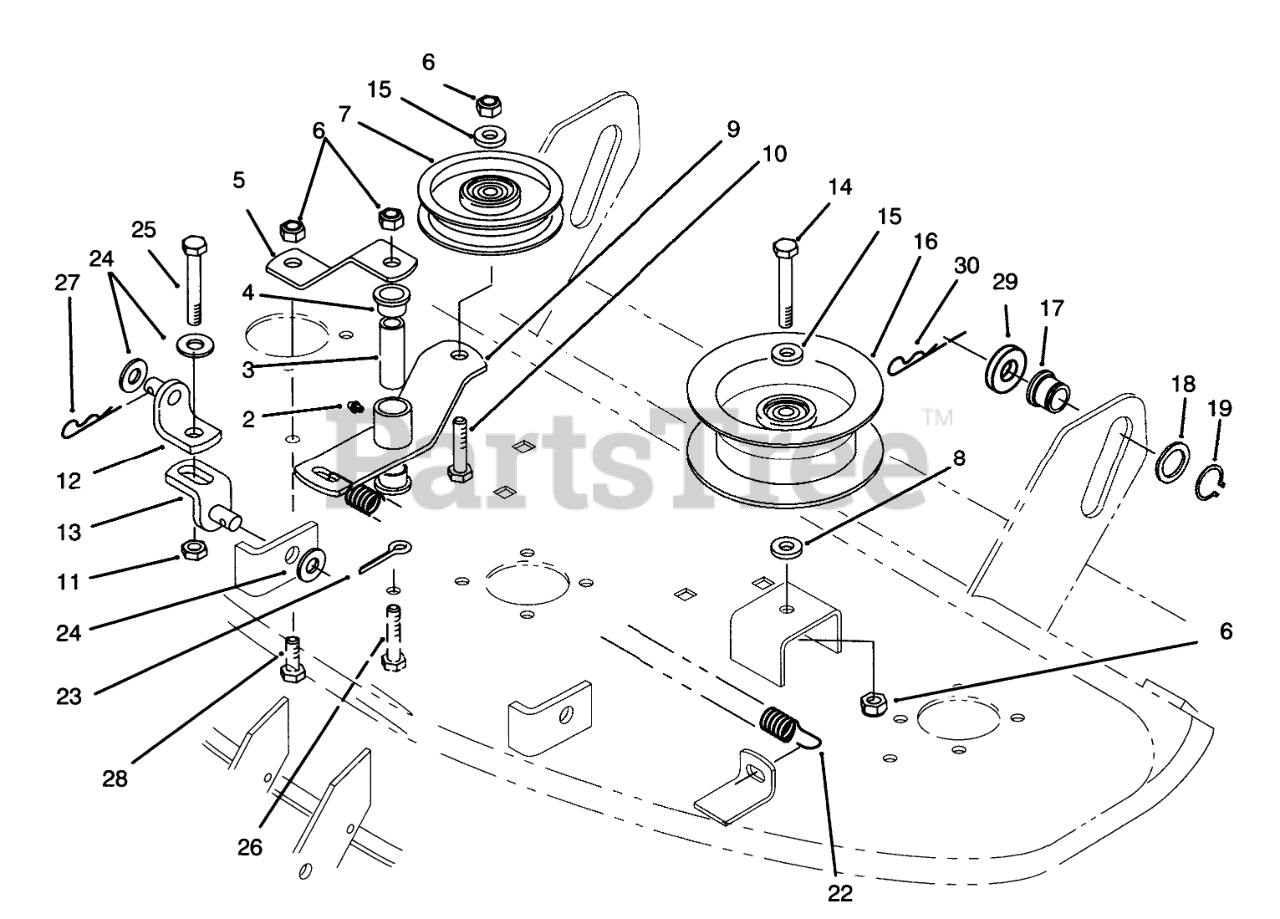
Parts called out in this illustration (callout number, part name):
2	FITTING-GREASE
3	SPACER
4	BUSHING
5	STRAP-BRACE
6	NUT-LOCK, NI
7	PULLEY-IDLER, FLAT
8	WASHER
9	Arm
10	SCREW-HH
11	NUT-JAM
12	BRACKET-LIFT, UPPER
13	BRACKET-LIFT, LOWER
14	SCREW-HH
15	WASHER-FLAT
16	PULLEY-IDLER
17	ROLLER-LIFT
18	Washer
19	RING-RETAINING
22	Spring-Extension
23	PIN-COTTER
24	WASHER-FLAT
25	SCREW-HH
26	SCREW-HH
27	Hairpin
28	SCREW-HH
29	WASHER-FLAT
30	Pin-Cotter
